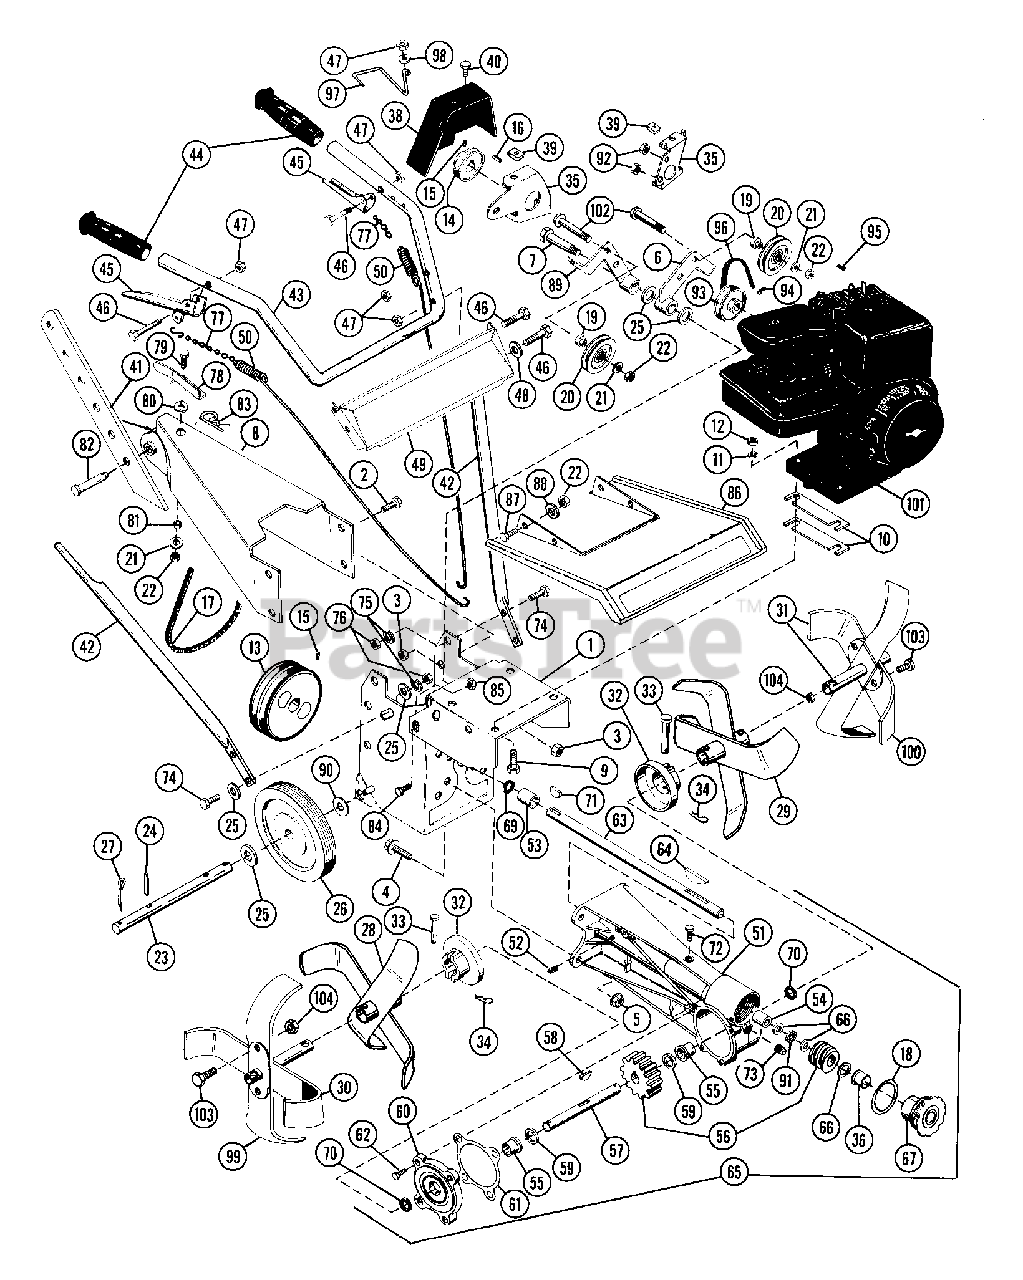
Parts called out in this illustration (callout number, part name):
1	FRAME
2	BLT-HEX .38-16X.75 PL GR2
3	NUT-LK-CTR .375-16 GR A PL
4	SCREW - FLG WIZ LOCK HH PL
5	NUT-LK-FLG .375-16 PL
6	IDLER ARM FWD
7	WHEEL SHOULDER BOLT
8	DEPTH STICK HOLDER
9	BLT-HEX .31-18X1.75 PL GR2
10	SHIM
11	WSHR-LK .312X.097 PL HVY
12	NUT-HEX .312-18
13	PLY-DBLV 5.50 X.75 W/KEY SALEM
14	ENGINE SHEAVE
15	SET SCREW
16	KEY-SQ .188X1.0X.188 SAE 8630
17	V-BELT, 4L-WRAPPED
19	SPCR, BRG .315X.50X.688X.281
20	IDLER
21	WSHR-FL-STL .38X.875X.083 PL
22	NUT-LK .312-18 GR A PL
23	AXLE ROD
24	PIN-ROLL .125X1.38
25	WSHR-FL-STL .531X1.062X.095 PL
27	PIN-COTR .12 X 1.25 PL
28	R H INNER TINE SPOOL
29	L H INNER TINE SPOOL
30	R H OUTER TINE SPOOL
31	L H OUTER TINE SPOOL
32	DUST CAP
33	CLEVIS PIN
34	PIN-HAIR INT .08X.38X1.42 YWZC
35	BELT GUARD BRACKET
36	BSHG-FLG .750X1.000X.750X1.132
38	BELT COVER
39	NUT-SPEED U-TYPE .250-20
40	BLT-HEX .25-20X.50 PL GR2
41	DEPTH STICK
42	LOWER HANDLE BAR
43	HANDLEBAR
44	GRIP
45	CLUTCH HANDLE
46	BLT-HEX .25-20X1.50 PL GR5
47	NUT-LK-CTR .250-20 PL
48	WSHR-FL-STL .268X.562X.046 PL
49	HANDLEBAR PANEL
50	SG-TENS .080X.25X31.6 WLD 35
51	GEARCASE - ALUMINUM
52	BREATHER
53	BSHG-SLV .750X1.000X1.000
54	BSHG-SLV .750X1.000X.750
55	BSHG-FLG 1.000X1.25X.75X1.50
56	WORM & GEAR SET
57	TINE SHAFT
58	KEY-WDRF .25X.687X.375
59	WSHR-HRD-THRS 1.007X1.542X.062
62	BLT-SERHFWH .31-18X.62 PL
63	WORM SHAFT
64	KEY-FTHR .188X1.38X.188
65	GEAR CASE ASSEMBLY
66	WSHR-HDND-THRST .755X1.40X.062
67	ADJUSTMENT PLUG
69	SEAL .750X1.000X.125
70	SEAL 1.000X1.980X.375
71	KEY-WDRF .188X.875X.375 SAE11
72	BLT-SCRHFWH .38-16X.50 PL
73	PIPE PLUG
74	BLT-HEX .38-16X1.00 PL
75	WSHR-LK .375X.115 HVY PL
76	NUT-HEX .375-16
77	CLUTCH CHAIN
78	RETAINER CLIP
79	BLT-HEX .31-18X.75 PL GR2
80	WAVE WASHER .515 X 1.00 X .125
81	SPACER BUSHING .5 X .32 X .21
82	CLEVIS PIN .437/.431X1.50 YWZC
83	PIN-HAIR INT .12X2.75
84	BLT-HEX .38-16X.75 PL GR5
85	NUT-LK TOP .375-16 GR C YWZC
86	TINE HOOD
87	BLT-HEX .31-18X.63 PL GR 2
88	WSHR-FL-STL.312X.734X.065PL
89	IDLER ARM REV.
90	SPACER .76 X .51 X .56
91	BRG-N THRST .754X1.24X.078
92	NUT-LK-FLG .250-20 PL
93	REVERSE SHEAVE
94	SCR-SET .25-20X.25 SKHCUPNY OH
95	KEY-WDRF .125X.625X.250 SAE5
96	V-BELT, 3L-WRAPPED
97	FORWARD BELT FINGER
98	WSHR-FL-STL.281X.62X.065 PL
99	R H TURBO-TINE
100	L H TURBO-TINE
102	BLT-RDHDSQNK .31-18X1.25 SHTPL
103	BLT-HEX .44-14X1.00 GR5
104	NUT-LK-TOP .437-14 GR C PL
